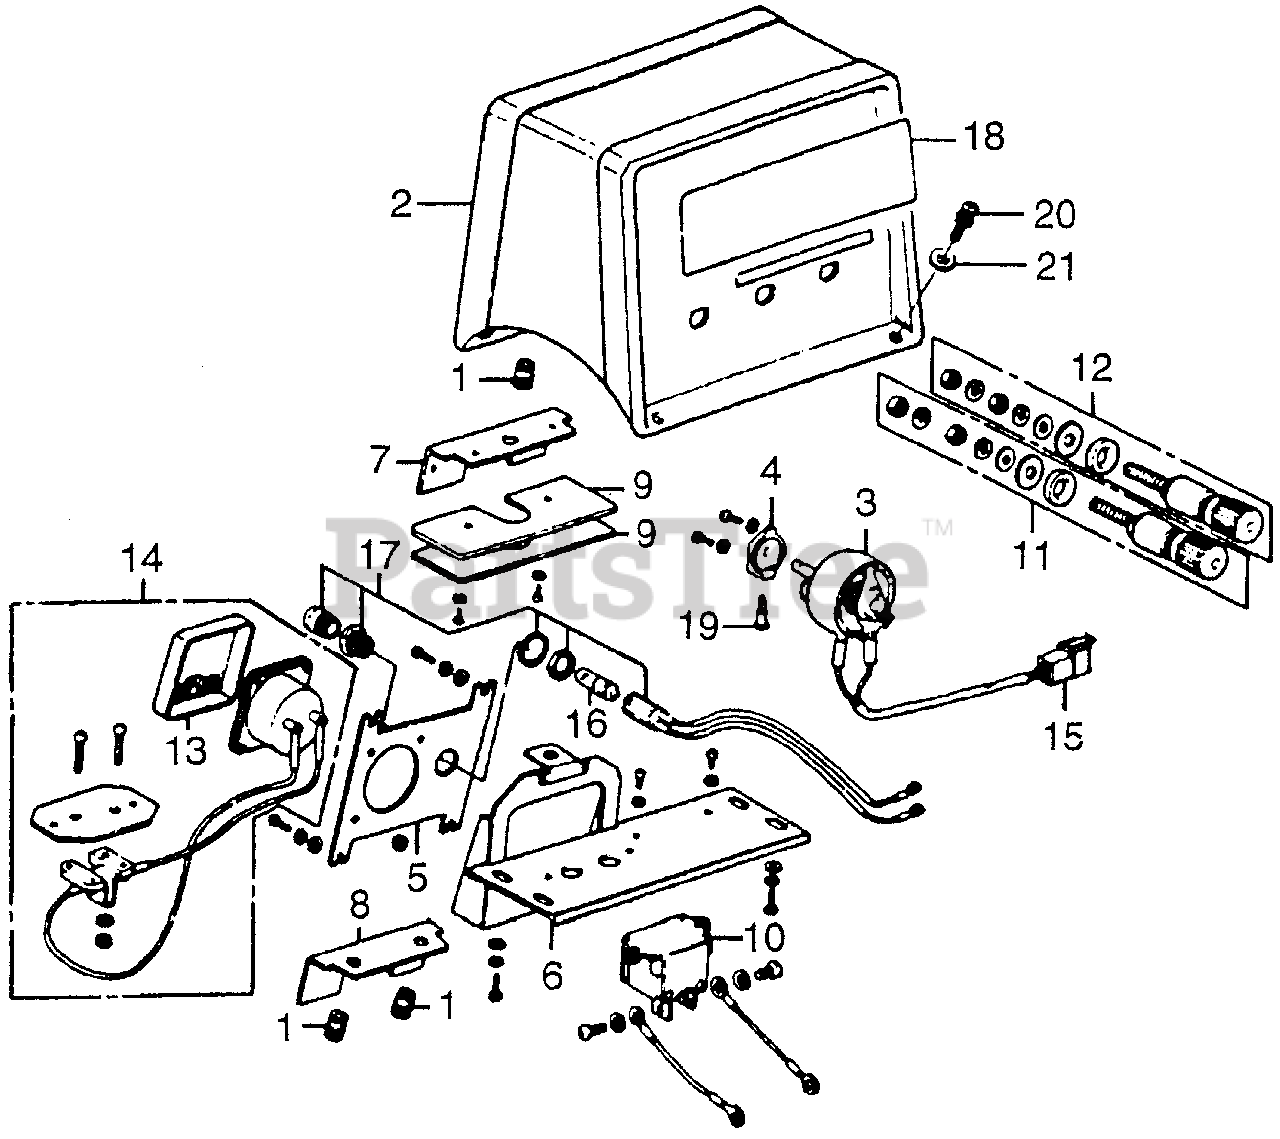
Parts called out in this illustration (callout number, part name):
1	RUBBER, FRICTION (NOT AVAILABLE)
2	BOX, CONTROL *R8* (BRIGHT RED)
3	RESISTOR, VARIABLE (NOT AVAILABLE)
4	KNOB, ADJUSTING
5	PANEL, METER
6	BASE ASSY., SETTING
7	STAY A, RUBBER SETTING
8	STAY B, RUBBER SETTING
9	WEIGHT, RUBBER SETTING
10	CONTROLLER, CURRENT
11	TERMINAL A, D.C. (NOT AVAILABLE)
12	TERMINAL B, D.C. (NOT AVAILABLE)
13	LENS, METER
14	VOLTMETER (NOT AVAILABLE)
15	CONNECTOR, MALE (2 POLE)
16	BULB (24V2W)
17	SOCKET ASSY., PILOT LAMP (NOT AVAILABLE)
18	PLATE, CAUTION (NOT AVAILABLE)
19	BOLT, KNOB (NOT AVAILABLE)
20	SCREW-WASHER (5X16)
21	WASHER, PLAIN (5MM)
